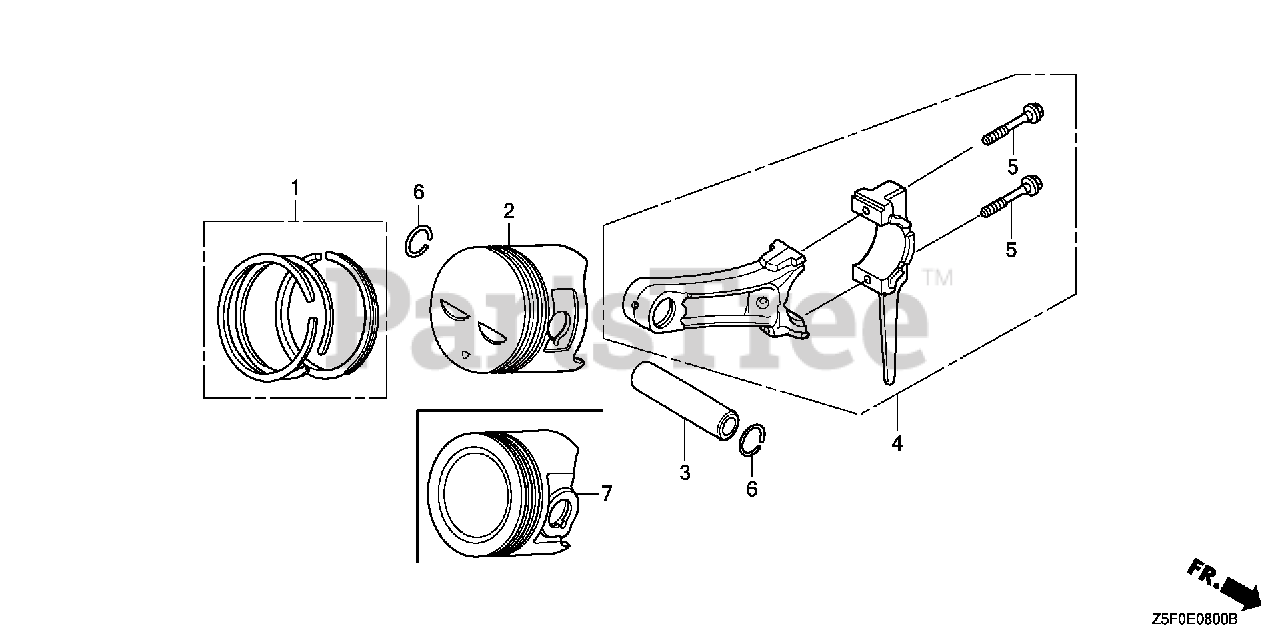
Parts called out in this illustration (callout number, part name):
1	RING SET, PISTON (STD) (TEIKOKU)
1	RING SET, PISTON (STD) (NIPPON)
1	RING SET, PISTON (0.25) (TEIKOKU)
1	RING SET, PISTON (0.25) (NIPPON)
1	RING SET, PISTON (0.50) (TEIKOKU)
1	RING SET, PISTON (0.50) (NIPPON)
1	RING SET, PISTON (0.75) (TEIKOKU)
1	RING SET, PISTON (0.75) (NIPPON)
2	PISTON (STD)
2	PISTON (0.25)
2	PISTON (0.50)
2	PISTON (0.75)
3	PIN, PISTON
4	ROD ASSY., CONNECTING (0.25 LOWER SIZE)
4	ROD ASSY., CONNECTING (STD)
5	BOLT, CONNECTING ROD
6	CLIP, PISTON PIN (18MM)
